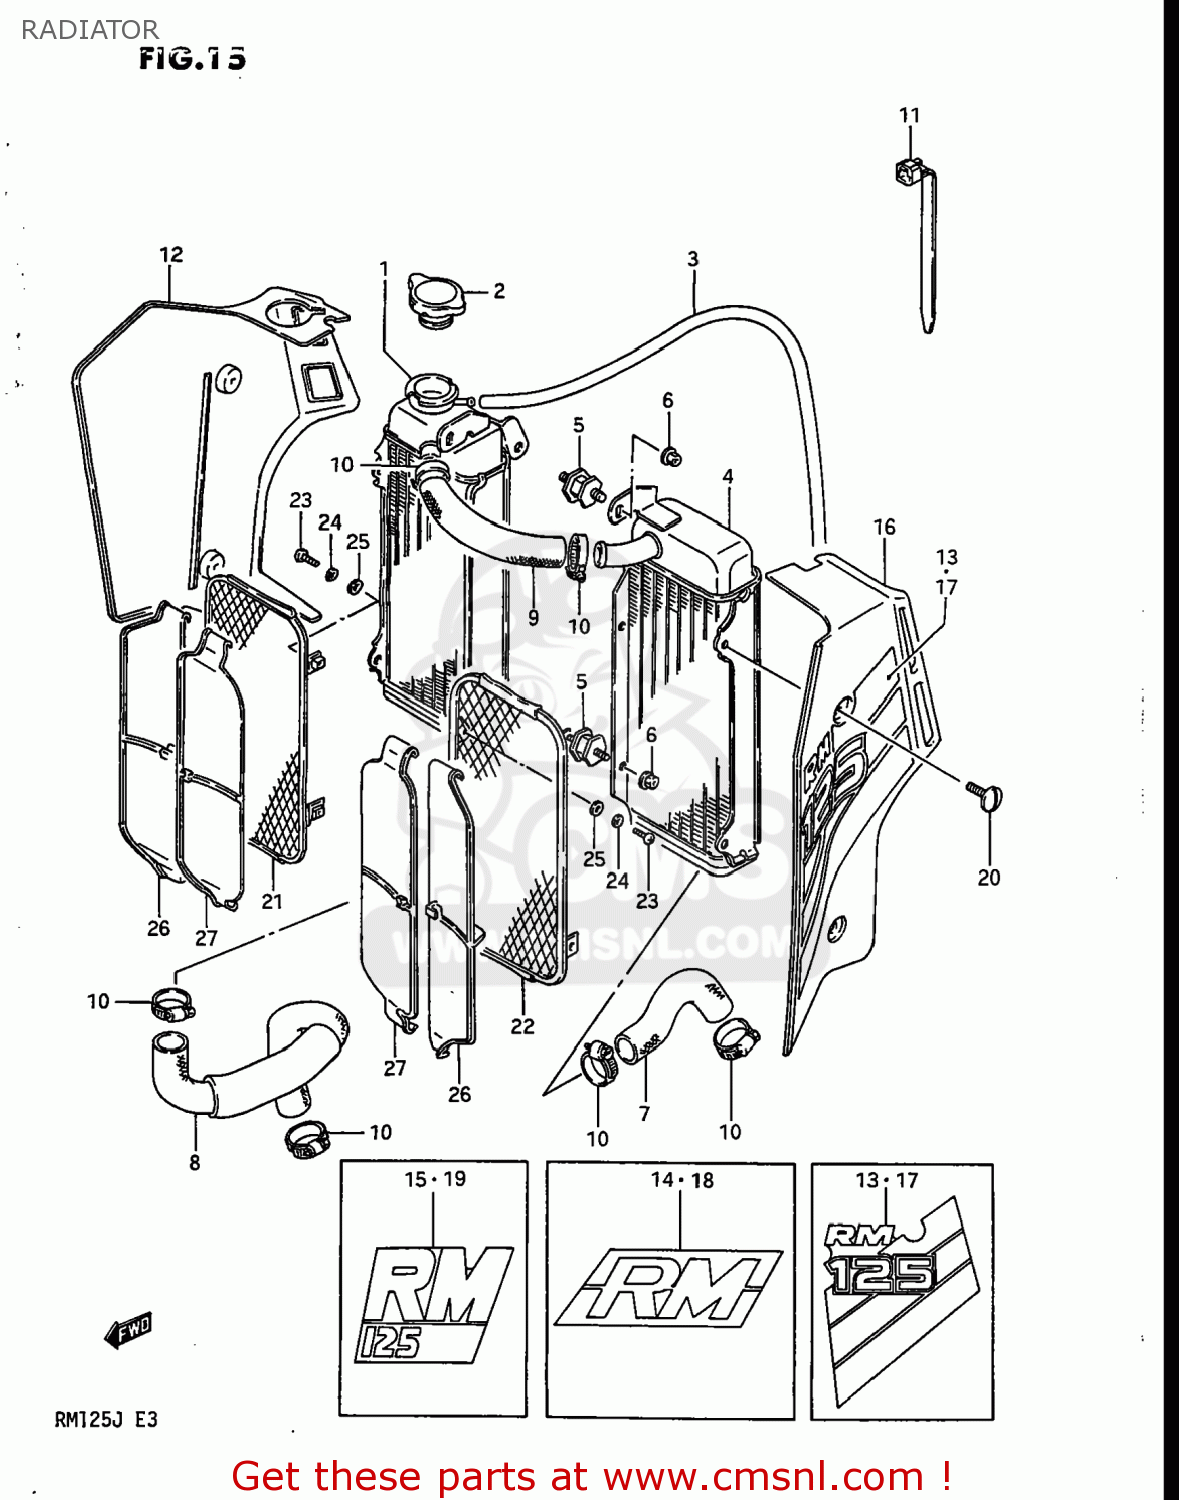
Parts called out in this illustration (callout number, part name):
1	RADIATOR COMP,WATER,RIGHT
2	CAP,RADIATOR 1.1
3	HOSE
4	RADIATOR COMP,WATER,LEFT
5	BOLT,RADIATOR CUSHION
6	NUT 6MM
7	HOSE,RADIATOR
8	HOSE,RADIATOR OUTLET
9	HOSE,RADIATOR JOINT
10	CLAMP
11	CLAMP(L:165)
12	COVER,RADIATOR
13	TAPE SET,RADIATOR COVER
14	TAPE SET,RADIATOR COVER STRIPE
15	EMBLEM,RADIATOR COVER
16	COVER,RADIATOR
17	TAPE SET,RADIATOR COVER
18	TAPE SET,RADIATOR COVER STRIPE
19	EMBLEM,RADIATOR COVER
20	SCREW(6X14)
21	BUMPER,RADIATOR,RIGHT
22	BUMPER,RADIATOR,LEFT
23	SCREW
24	WASHER,LOCK
25	WASHER
26	LOUVER,RADIATOR NO.1
27	LOUVER,RADIATOR NO.2
